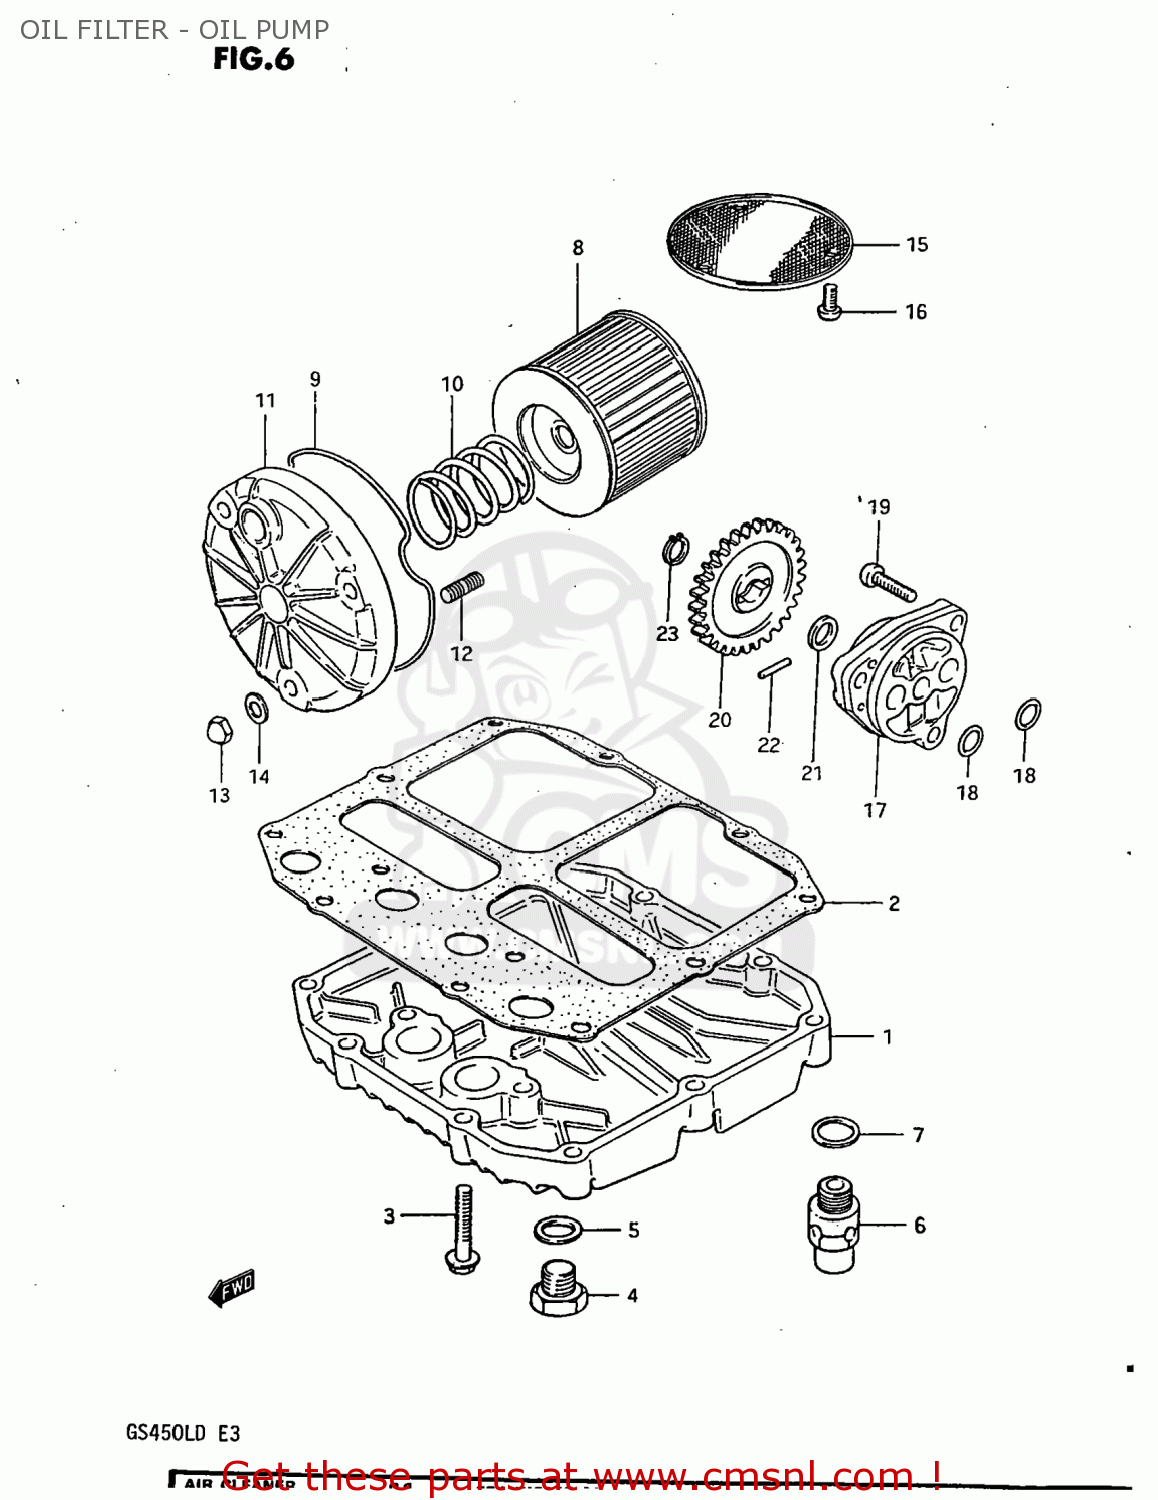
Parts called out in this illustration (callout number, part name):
1	PAN,OIL
2	GASKET,OIL PAN (MCA)
3	BOLT
4	PLUG
5	GASKET(14X19.2X2) (NAS)
6	REGULATOR ASSEMBLY,ENGINE
7	WASHER
8	FILTER ASSY,ENGINE OIL
9	O RING,OIL FILTER CHAMBER CAP
10	SPRING
11	CAP,OIL FILTER
12	STUD 6X20
13	NUT
14	WASHER
15	STRAINER,ENGINE OIL
16	SCREW 6X12
17	PUMP ASSY,ENGINE OIL
18	O RING(D:1.9,ID:13)
19	SCREW
20	GEAR,OIL PUMP DRIVEN
21	SHIM
22	PIN(4X15.8)
23	CIRCLIP
